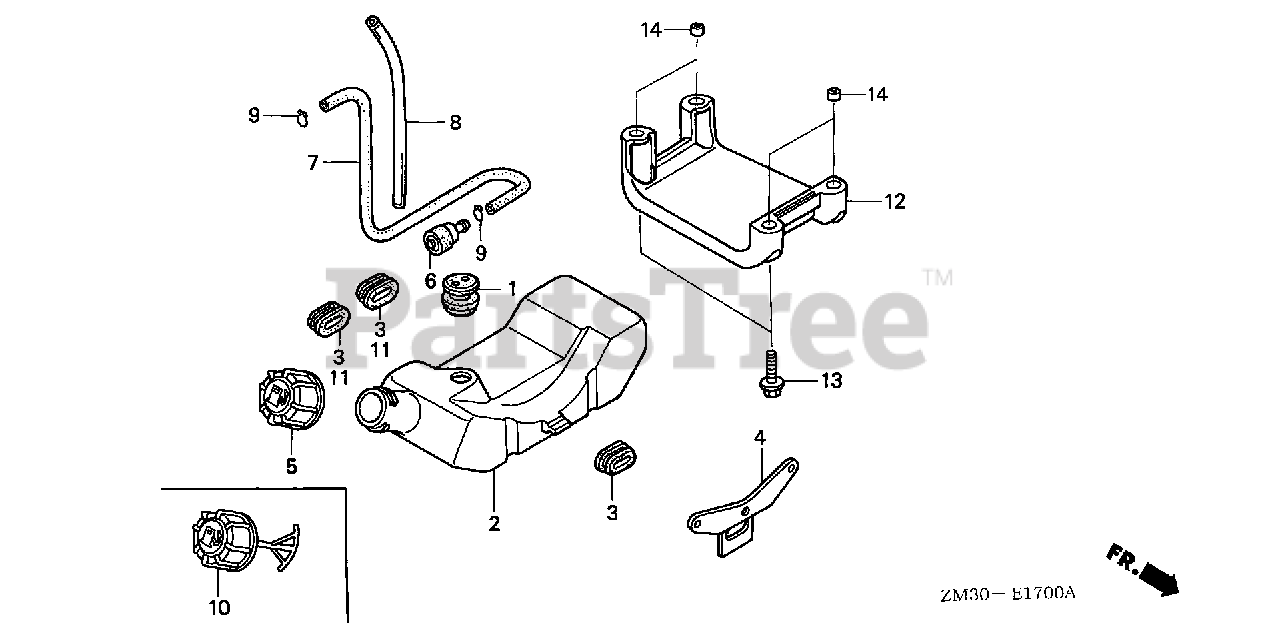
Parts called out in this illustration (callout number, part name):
1	GROMMET, FUEL TUBE
2	TANK, FUEL
3	RUBBER A, TANK MOUNTING
4	STAY, FUEL TANK
5	CAP ASSY., FUEL TANK
6	FILTER, FUEL
7	TUBE, FUEL
8	TUBE, FUEL RETURN
9	CLIP, TUBE
11	RUBBER A, TANK MOUNTING
11	RUBBER B, TANK MOUNTING
